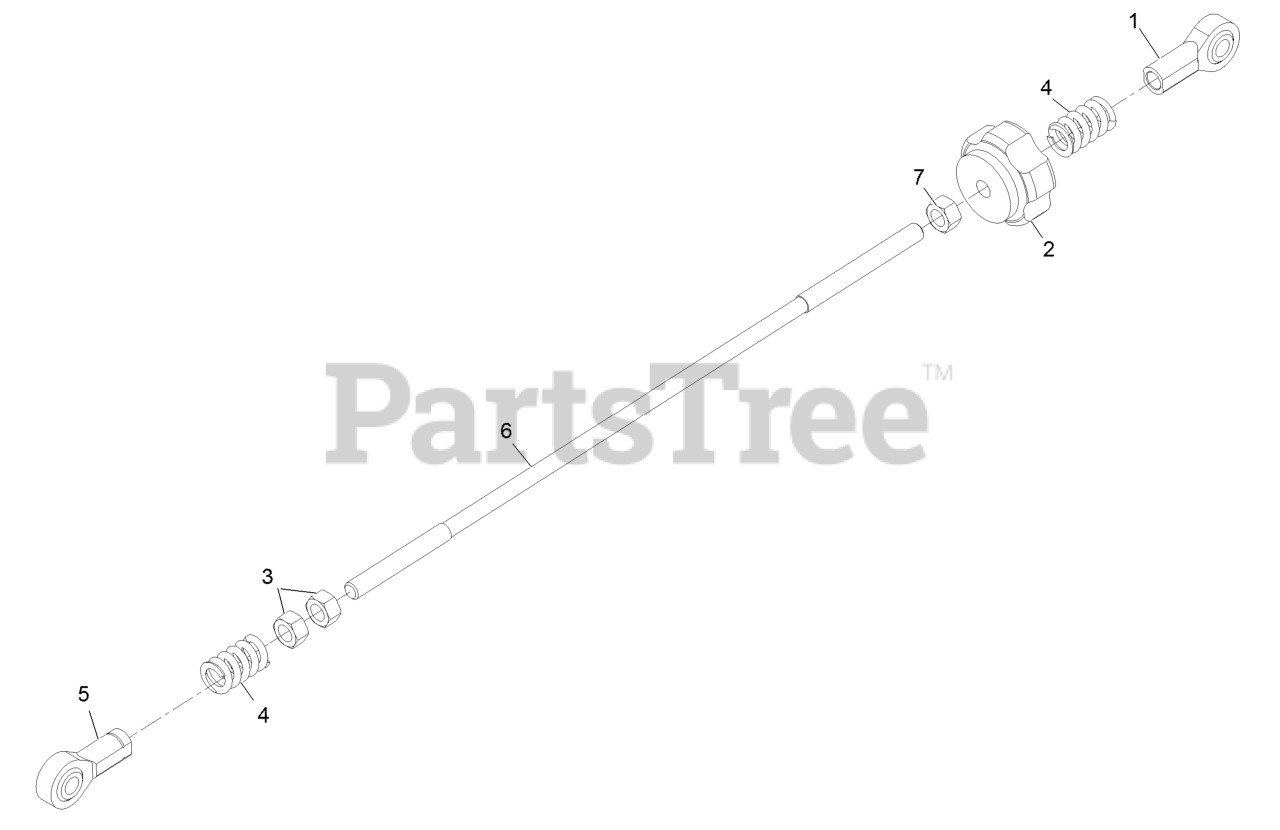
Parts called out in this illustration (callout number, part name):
1	BALLJOINT-RH
2	KNOB-TRACKING
4	SPRING-COMPRESSION
5	BALLJOINT-LH
6	LINK,TRACKING ROD XP
7	NUT-HEX
